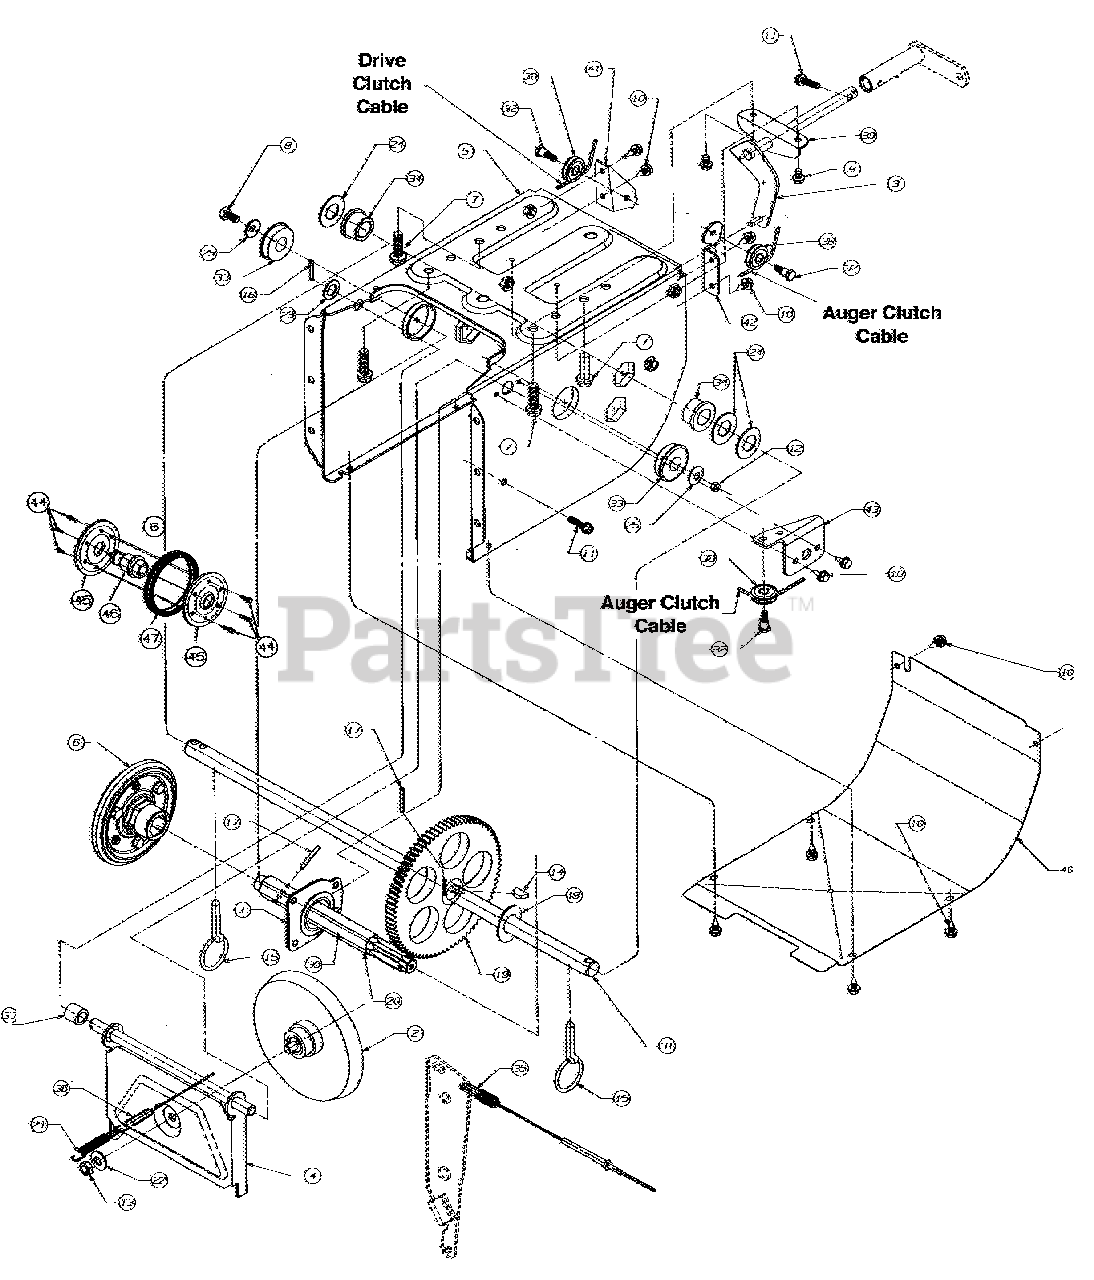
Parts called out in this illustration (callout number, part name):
1	Bearing Ass'y.
2	Ass'y., Friction Wheel Disc
3	Rod Shift, Wheel Drive
7	Hex Self-Tap Screw
8	Screw-Hex Lock
9	Scr., Hex Wash. Hd., TT 1/4-20 x .5"
10	Hex Self-Tap Scr.
11	Screw, Hex
12	Nut-Jam Hex
15	Pin, Klick
16	Pin, Cotter
17	Pin, Roll
18	Washer-Flat
20	Shaft, Hex
21	Extension Spring
22	Washer, Bell
23	Flat Washer
24	Washer, Flat
25	Washer, Bell
30	Lubricant
32	Screw, Shoulder
33	Bearing, Ball
34	Flange Bearing
35	Cable, Auger
36	Cable, Clutch
38	Roller, Cable
45	Friction Plate
46	Friction Wheel Hub
47	Friction Wheel Rubber
